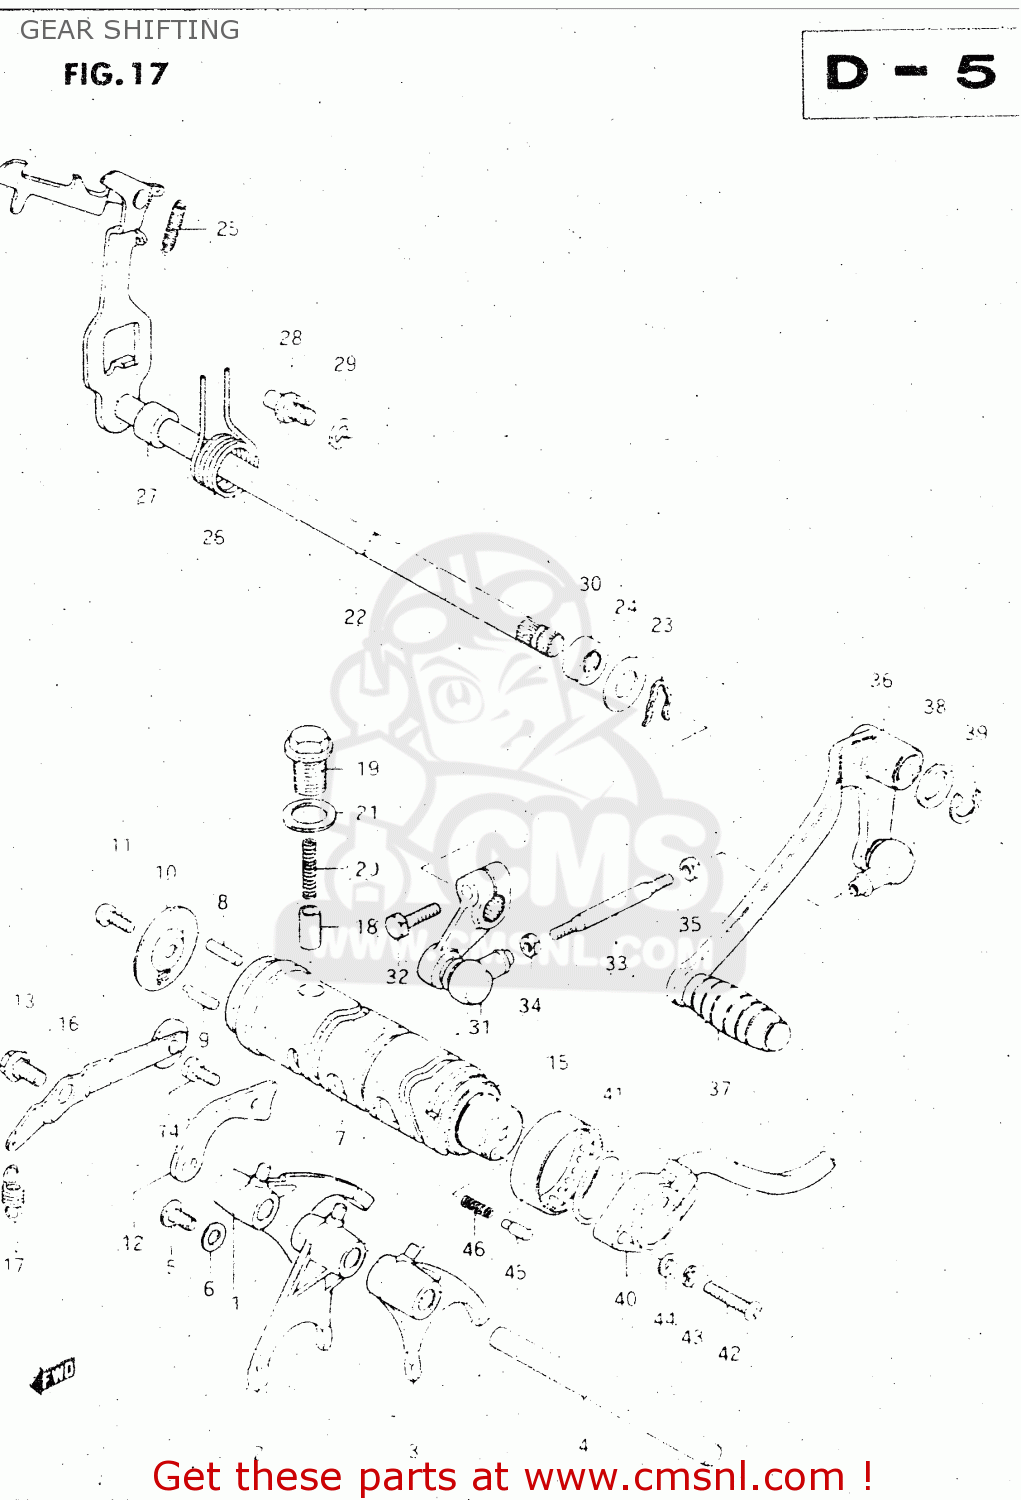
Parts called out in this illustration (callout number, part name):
1	FORK,GEAR SHIFT NO.1
2	FORK,GEAR SHIFT NO.2
3	FORK,GEAR SHIFT NO.2
4	SHAFT,GEAR SHIFT FORK
5	SCREW
6	WASHER
7	CAM,GEAR SHIFT
8	PIN(4X18.5)
9	PIN,SPRING(4X28)
10	RETAINER,GEAR SHIFT CAM DR PIN
11	SCREW
12	GUIDE,GEAR SHIFTING CABLE
13	BOLT
14	BOLT
15	BEARING(40X47X12)
16	STOPPER,GEAR SHIFT CAM NO.1
17	SPRING
18	STOPPER,GEAR SHIFT CAM NO.2
19	HOLDER,GEAR SHIFT CAM STOP SPR
20	SPRING
21	GASKET(14X19.2X2) (NAS)
22	SHAFT,GEAR SHIFT
23	SPRING,RETAINER
24	WASHER (12.5X27X1.6)
25	SPRING
26	SPRING
27	SPACER(12X20X15.3)
28	STOPPER,GEAR SHIFT CAM
29	WASHER
30	OIL SEAL
31	ARM,GEAR SHIFT LINK
32	BOLT
33	ROD,GEAR SHIFT LINK
34	NUT
35	NUT
36	LEVER ASSEMBLY,GEAR SHIFTING
37	RUBBER,GEAR SHIFT PEDAL
38	WASHER(12.5X20X1)
39	CIRCLIP
40	TERMINAL BASE ASSY,GEAR SHIFT
41	O-RING (D:2.4 ID:26.2)
42	SCREW 5X20
43	LOCK WASHER
44	WASHER
45	PIN(5X15.5)
46	SPRING
